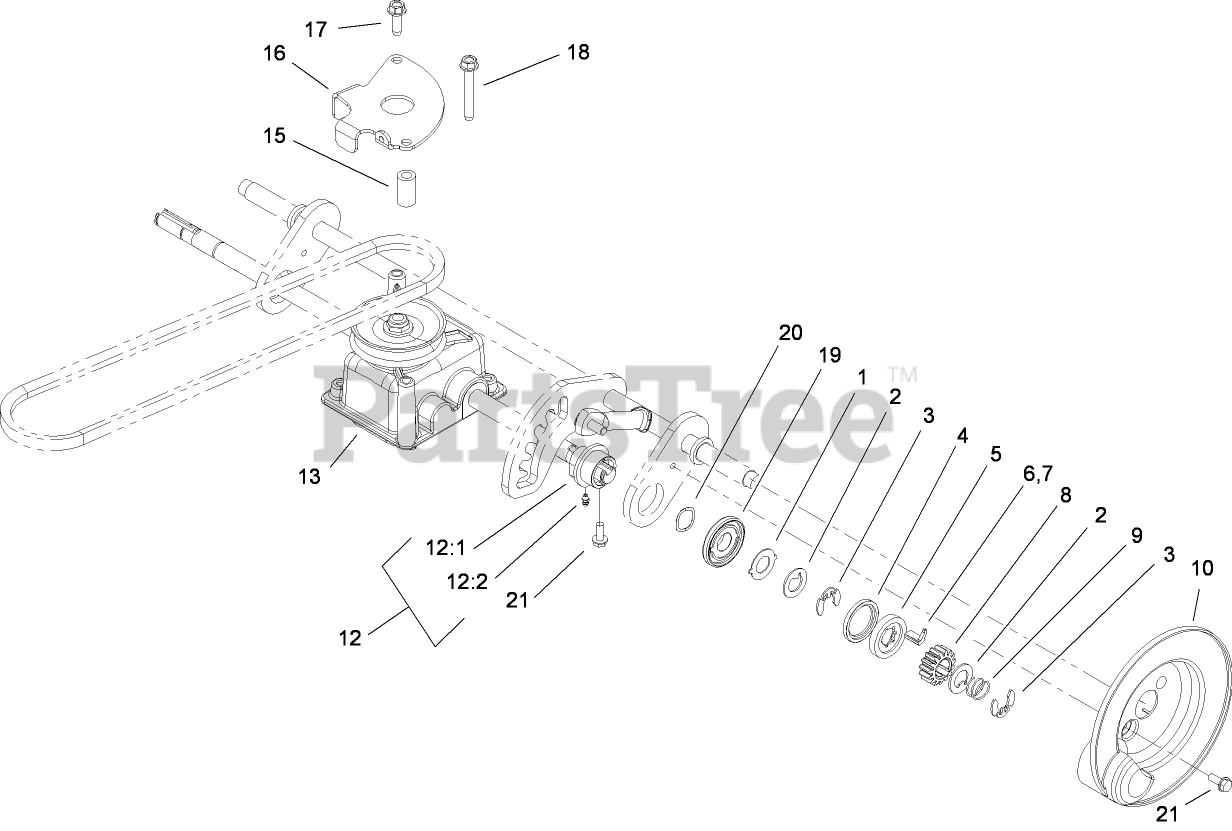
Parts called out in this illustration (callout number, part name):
1	WASHER-ARM, PIVOT
2	WASHER-THRUST, KEYED
3	RING-RETAINING,CLIP
4	RING-FRICTION
5	WASHER-CLUTCH
6	KEY-ROCKING, RH
7	KEY-ROCKING, LH
8	GEAR-PINION
9	SPRING-COMPRESSION
10	COVER-GEAR
12	BUSHING ASM
12:2	FITTING-GREASE
13	GEAR CASE ASM
15	BUSHING-PLATE, ACTUATOR
16	GUIDE-TRANSMISSION
17	SCREW-HWHTF
18	SCREW-HWHTF
19	RETAINER-RING
20	WASHER-WAVE
21	SCREW-TAPTITE
